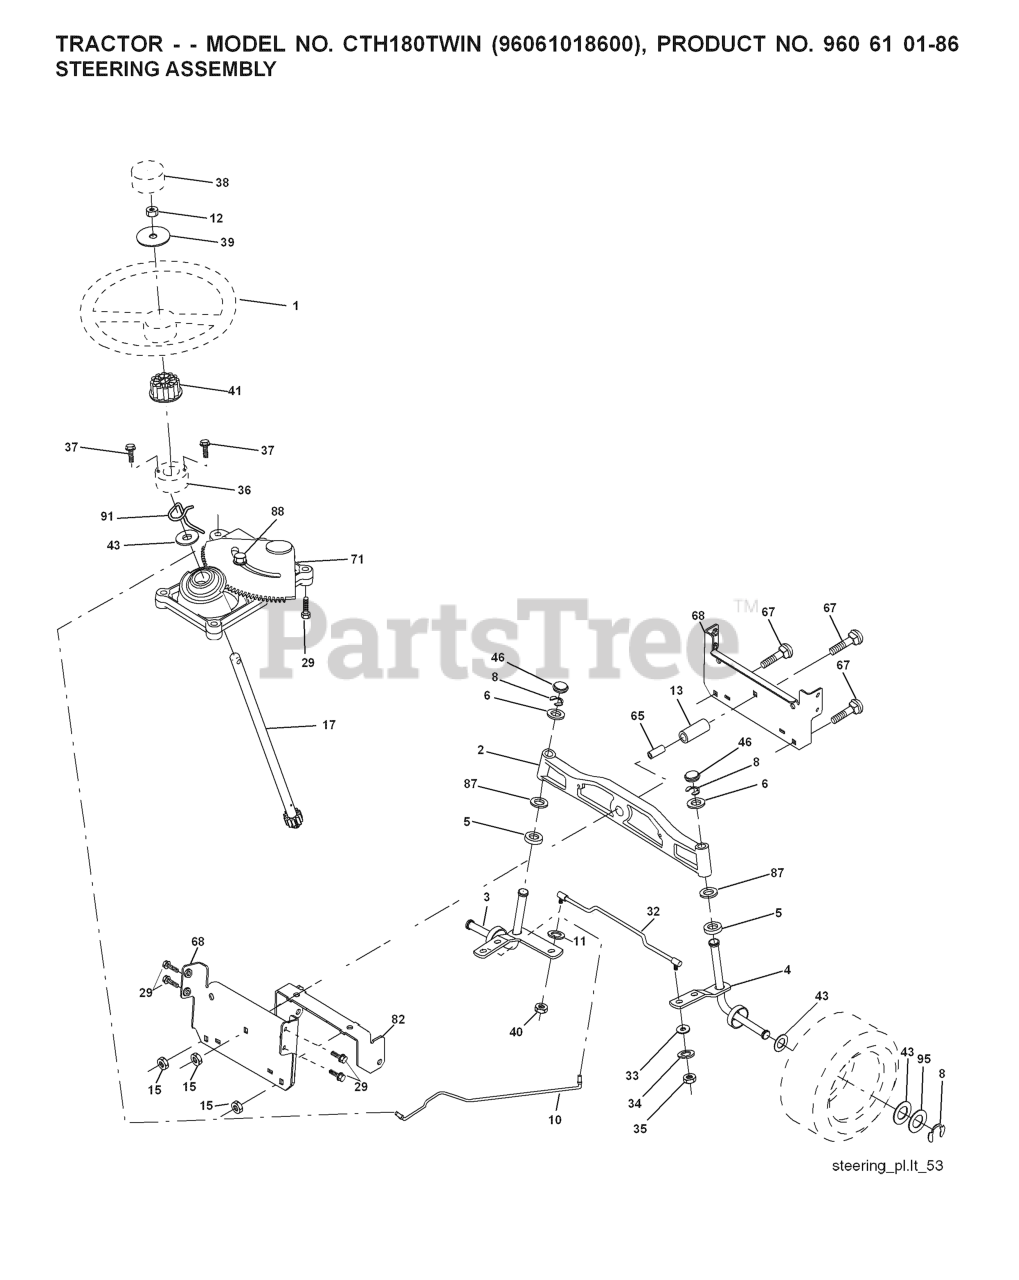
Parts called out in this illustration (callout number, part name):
1	STEERING WHEEL
2	AXLE ASSY FRONT
3	SPINDLE.ASM.LH.15"TIRES
4	SPINDLE.ASM.RH.15"TIRES
5	THRUST WASHER
10	DRAGLINK.15".TIRES.2001
11	WASHER, LOCK 3/8
12	NUT.HEX.1/2-20
13	TUBE, PIVOT AXLE
15	NUT
17	SHAFT ASM STRG
29	SCREW, 3/8-16X3/4
33	WASHER M
34	WASHER.LOCK.HVY.HLCL.SPR.5/16
35	NUT, CROWNLOCK
36	BUSHING, STRG. BLK
37	SCREW.TT.#10-32X.5.3/8.FLANGE
38	INSERT.CAP.STRG.WH.GRAY
39	WASHER 9/16"ID, 2 3/8"OD
40	NUT CROWNLOCK 3/8-24
41	ADAPTER, WHEEL STNG..
46	CAP.SPINDLE.BLACK
65	SPACER BRACE AXLE
67	BOLT CARRIAGE
68	BRACE.AXLE.15"TIRES
71	STEERING ASM
82	BRACKET.SUSP.CHASSIS.FRONT.15
87	WASHER, FLAT .781 X 1 1/2"
88	BOLT, SHOULDER 7/16-20
91	CLIP.STEERING
95	WASHER.HARDENED
